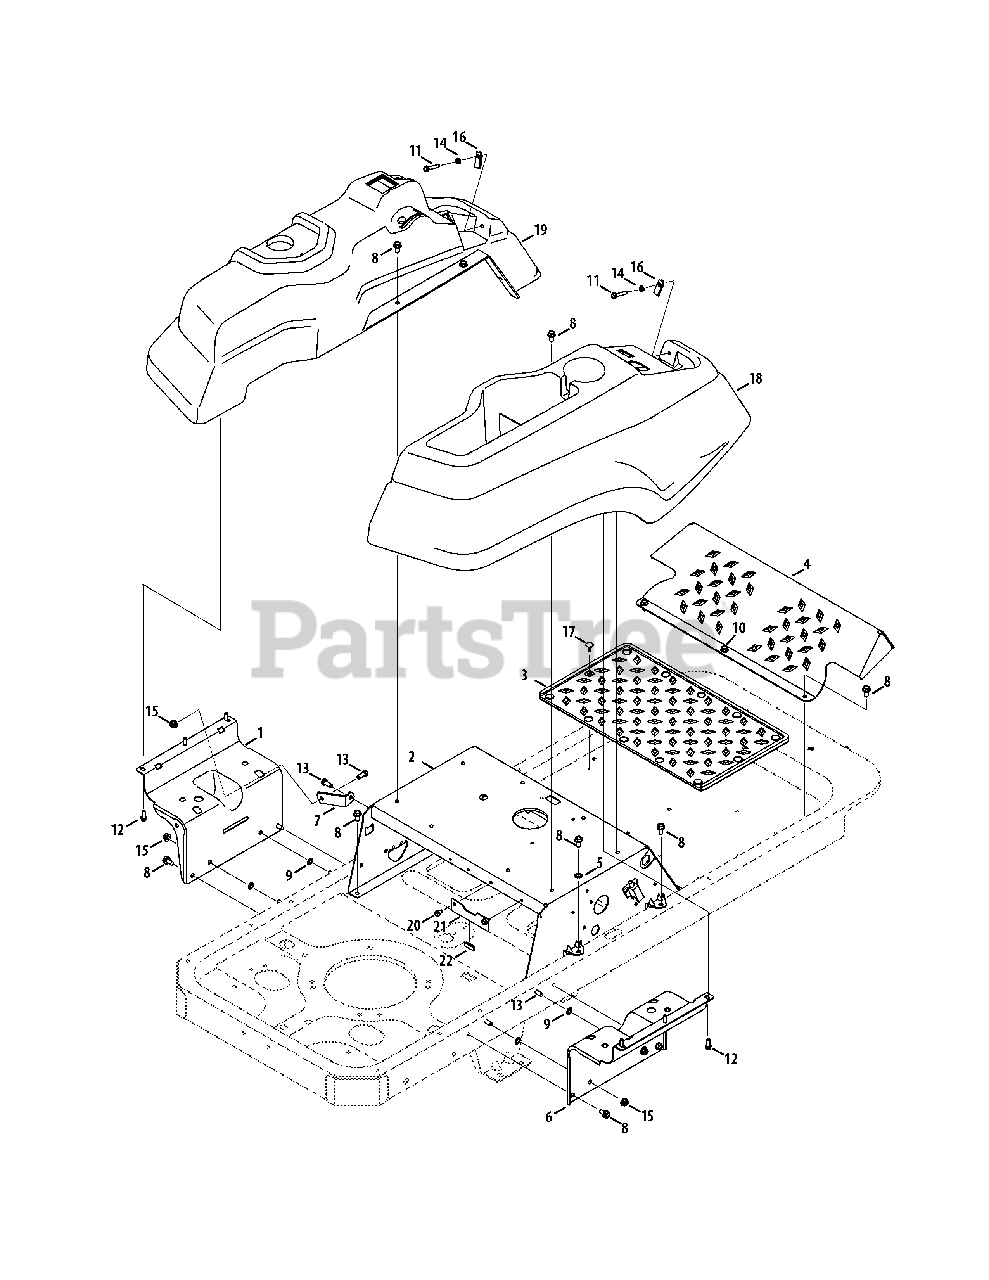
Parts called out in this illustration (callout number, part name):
1	Console Mount Bracket
6	Console Mount Bracket
7	Fuel Tank Support Bracket
8	Hex Washer Screw, 5/16-18 x .750
9	Speed Nut, .3125
10	Hex Washer Screw, 5/16-18 x .825
11	Hex Washer Screw, 1/4-20 x 1.500
12	Hex Washer Screw, 1/4-15 x .750
13	Hex Screw, 5/16-18 x .75
14	Jam Nut, 1/4-20
15	Flange Lock Nut, 5/16-18
16	U-Type Nut, 1/4-20
17	Ratchet Clip, .250
18	RH Console
20	Hex Screw, 1/4-20 x .5
21	Battery Hold-Down
22	Trim Strip
